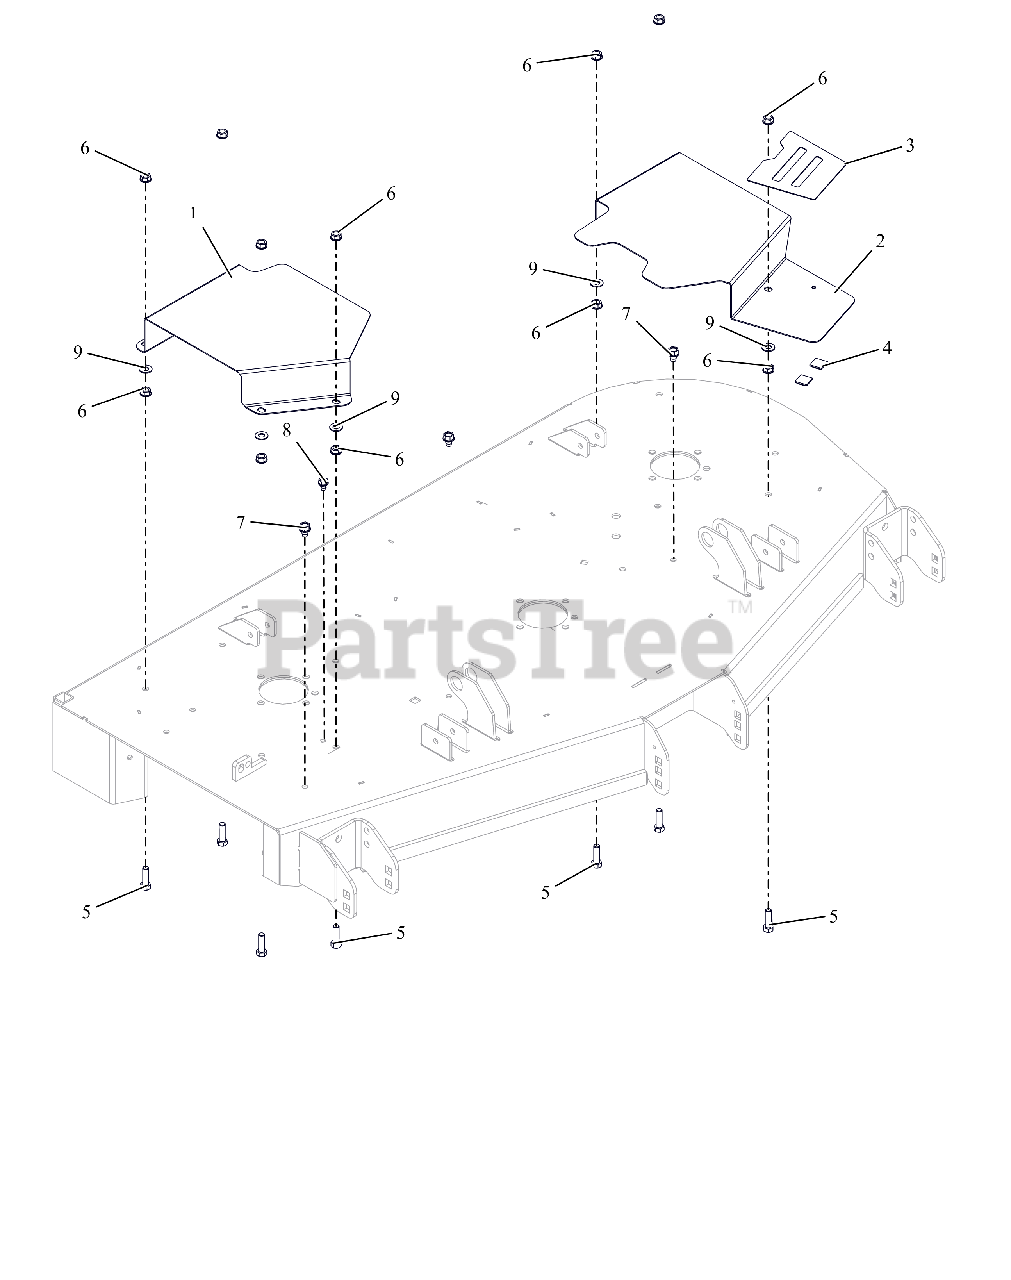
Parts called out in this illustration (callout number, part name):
1	COVER, BELT 52" & 60" RIGHT
2	COVER, BELT 52" LEFT
3	GRIP, TAPE 52-60 BELT COVER
5	BLT, HEX .38-16X1.25 G5 ZCC
6	NUT, SPNLK-FLG .38-16 G5 ZCC
7	SCR,TAP .375-16X.50 HWH TR ZCC
8	SCR,TAP .312-18X.50 HWH TR ZCC
9	WSHR,FLT .406X.812X.065 ZCC
